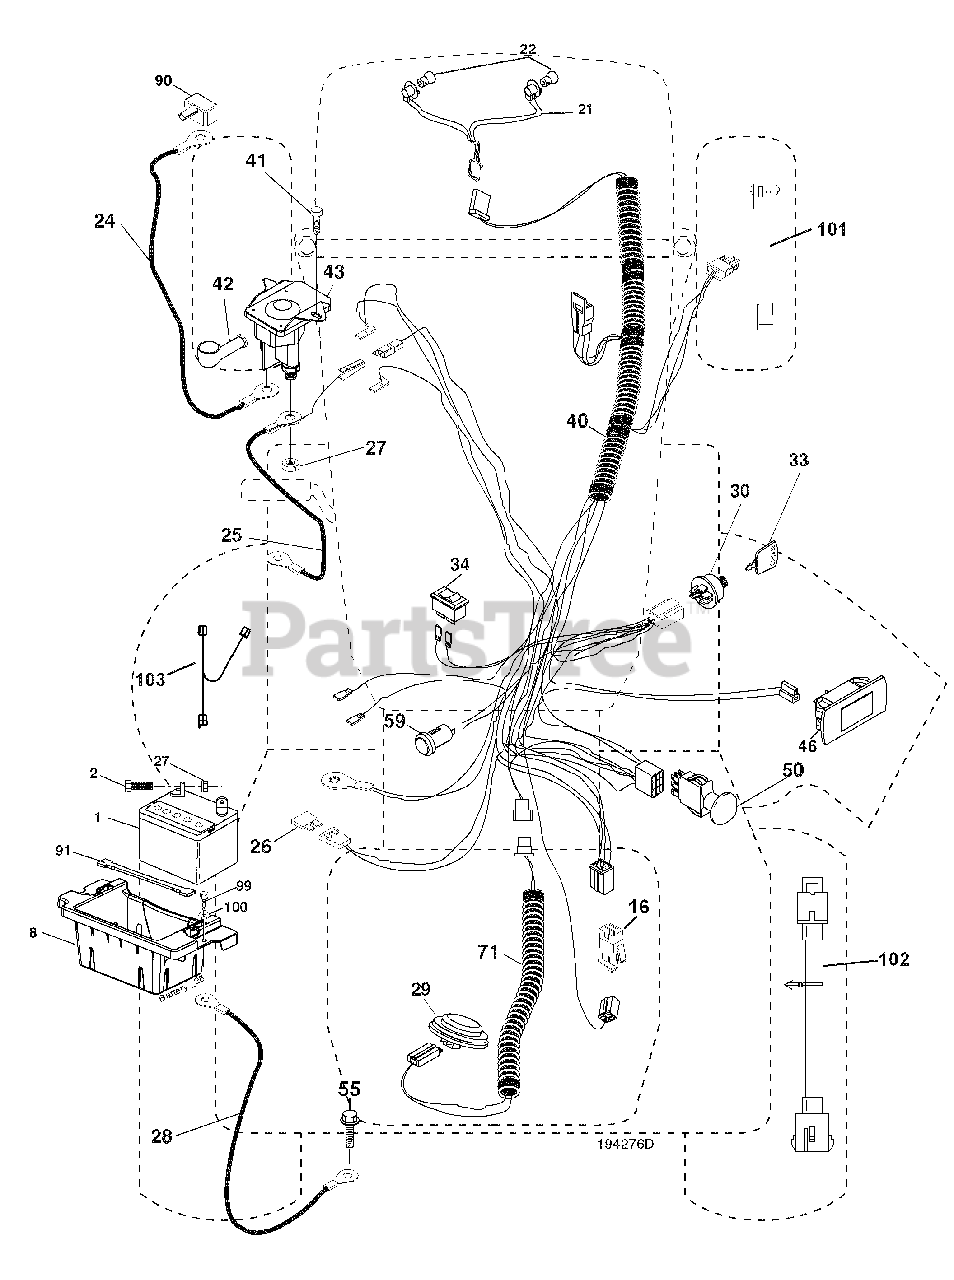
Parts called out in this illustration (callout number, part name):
1	Battery
2	Bolt Hex Hd 1/4-20 unc x 3/4
8	Battery Box
16	Switch Interlock
21	Harness Socket Light
22	Bulb, Light # 1156
24	Cable Battery
25	Cable Starter
27	Nut Keps Hex 1/4-20 unc
28	Cable Ground 21" Blk 6 Ga.
29	Switch Seat
30	Switch Ign
33	Key Ign Molded Generic
34	Switch Light/Reset
40	Harness Ign. Dash
41	Screw Thd Cut 1/4-20 x 1/2
42	Cover Terminal Red
43	Solenoid
46	Gauge Hourmeter
50	Switch PTO
55	Screw Thdrol 5/16-18 x 3/4
59	Outlet 12-Volt
71	Harness Ign
90	Cover Terminal Battery
91	Strap Battery
99	Screw Hexwsh Thdrol 1/4-20 x 3/4
100	Washer 9/32 x 7/8 x 16 Ga.
101	Pigtail MATNLK
102	Harness Pigtail K46 Tex ROS
103	Harness Pigtail 12V Outlet
